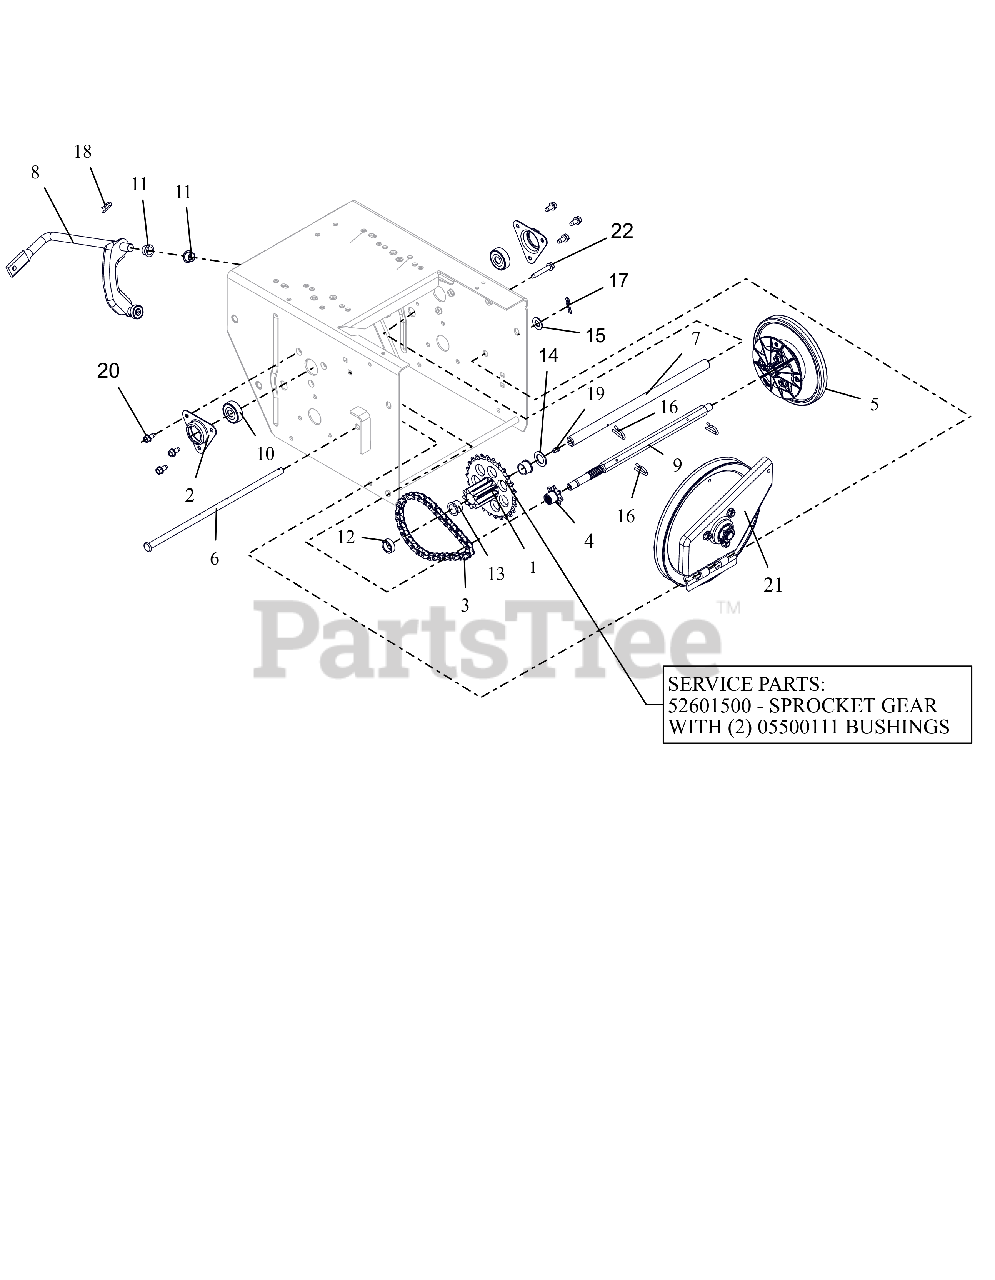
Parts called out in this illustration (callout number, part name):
1	PINION & SPROCKET
1	PINION & SPROCKET W/BUSHINGS
2	FLANGE, BEARING
3	CHAIN - #41, 32 PITCHES
4	SPROCKET, PINION 7T W/SPLINE
5	DISC, FRICTION DRIVE-ASSEMBLY
6	PIN, PIVOT
7	SHAFT, PINION-HARDENED
8	ARM, SHIFT - ASSEMBLY
9	SHAFT, HEX - HEAT TREATED
10	BRG-BALL .437X1.375X.437
11	BUSHING, POLYLINER-.50 SPLIT
12	BSHG-SLV, .635X.880X.305
13	BSHG-FLG .625X.750X.500X.875
14	WSHR, FLT .630X1.005X.062 ZCC
15	WSHR,FLT .406X.812X.065 ZCC
16	PIN, SPRING CLIP
17	PIN, HAIR #225 .072X1.09
18	CLIP, SPRING
19	ZERK,FITTING .25X.125 DRIVE IN
20	SCR-TAP .25-20X.50 HWH ZCC
21	PLATE, SWING ASSEMBLY-DEEP
22	SCR,TAP .25-20X1.50 HWH TR ZCC
